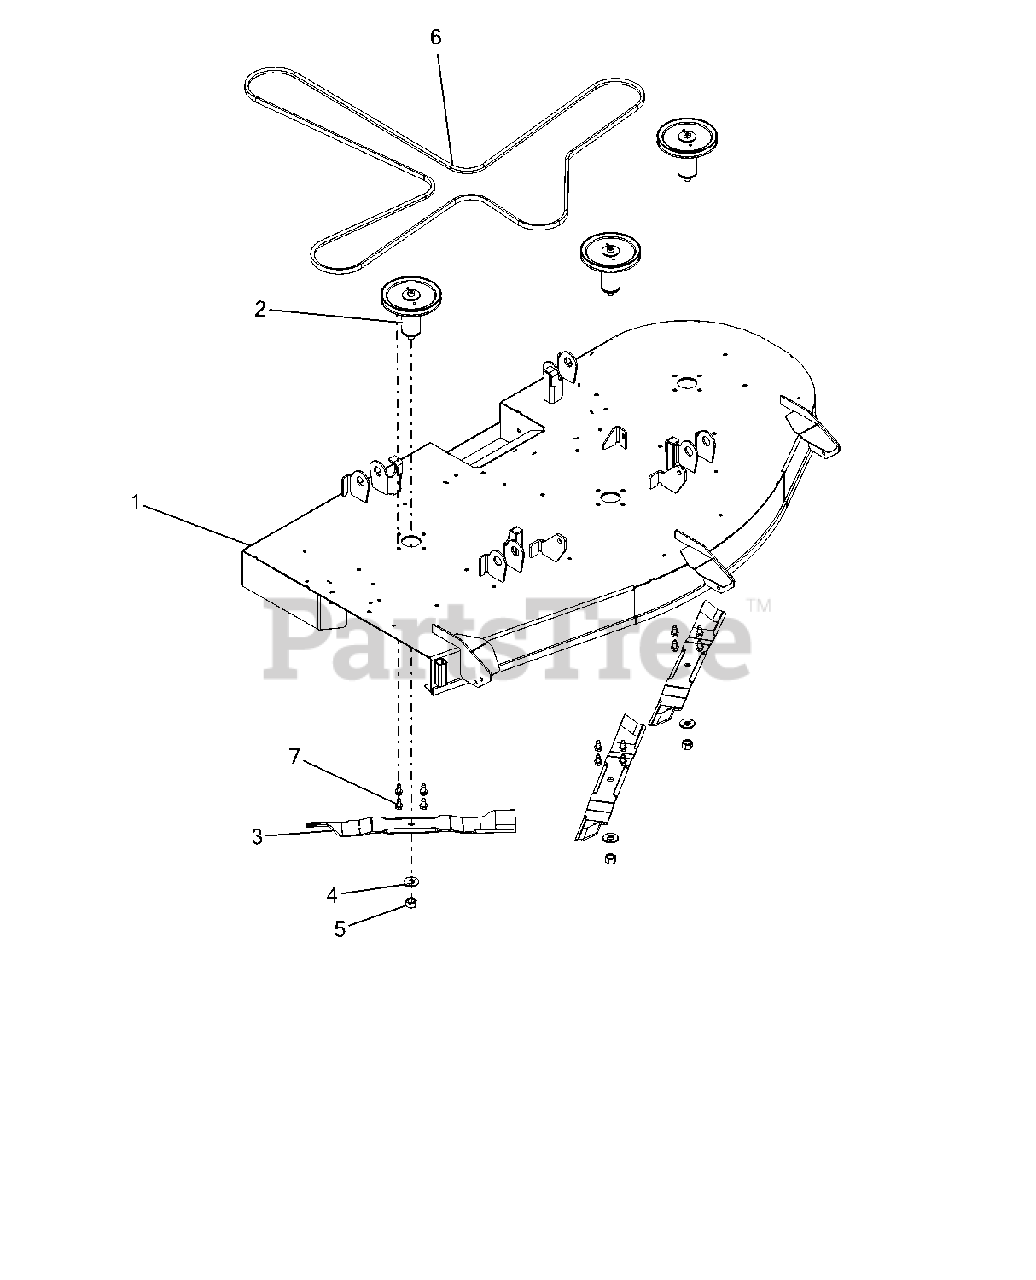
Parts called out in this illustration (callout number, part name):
1	KIT, 60" ARIENS DECK W/DECALS
2	KIT, DECK SPINDLE ASM-60
3	BLADE, 21" 35 DEG
4	WSHR-BLVL .669X1.535X.138
5	NUT-HEX .62-18 YWZC
6	BELT, HA
7	@SCR-TAP .38-16X.75 HWH TR YWZ
